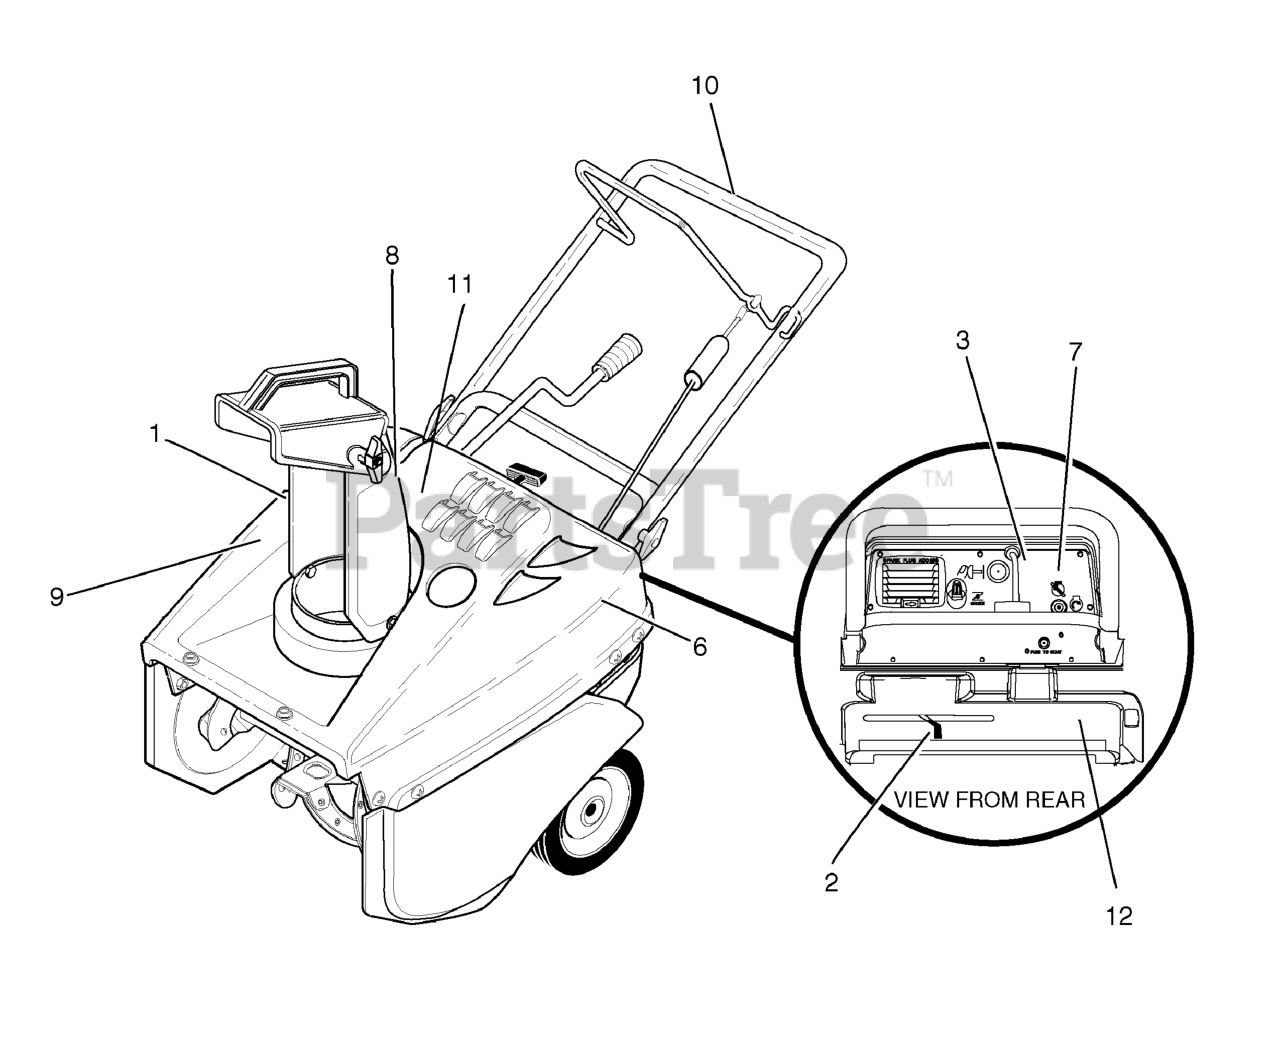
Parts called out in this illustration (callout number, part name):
1	DECAL, EPA 5HP, MASS *
2	DECAL, ELECTRIC START
3	DECAL, CONTROL PANEL
6	DECAL, HOT SURFACE
7	DECAL, ELECTRIC START
8	DECAL, DANGER CHUTE
9	DECAL, DANGER AUGER, FOOT
10	DECAL, AUGER ENGAGE
12	DECAL, McCULLOCH
13	DECAL, 104db EXPORT *
